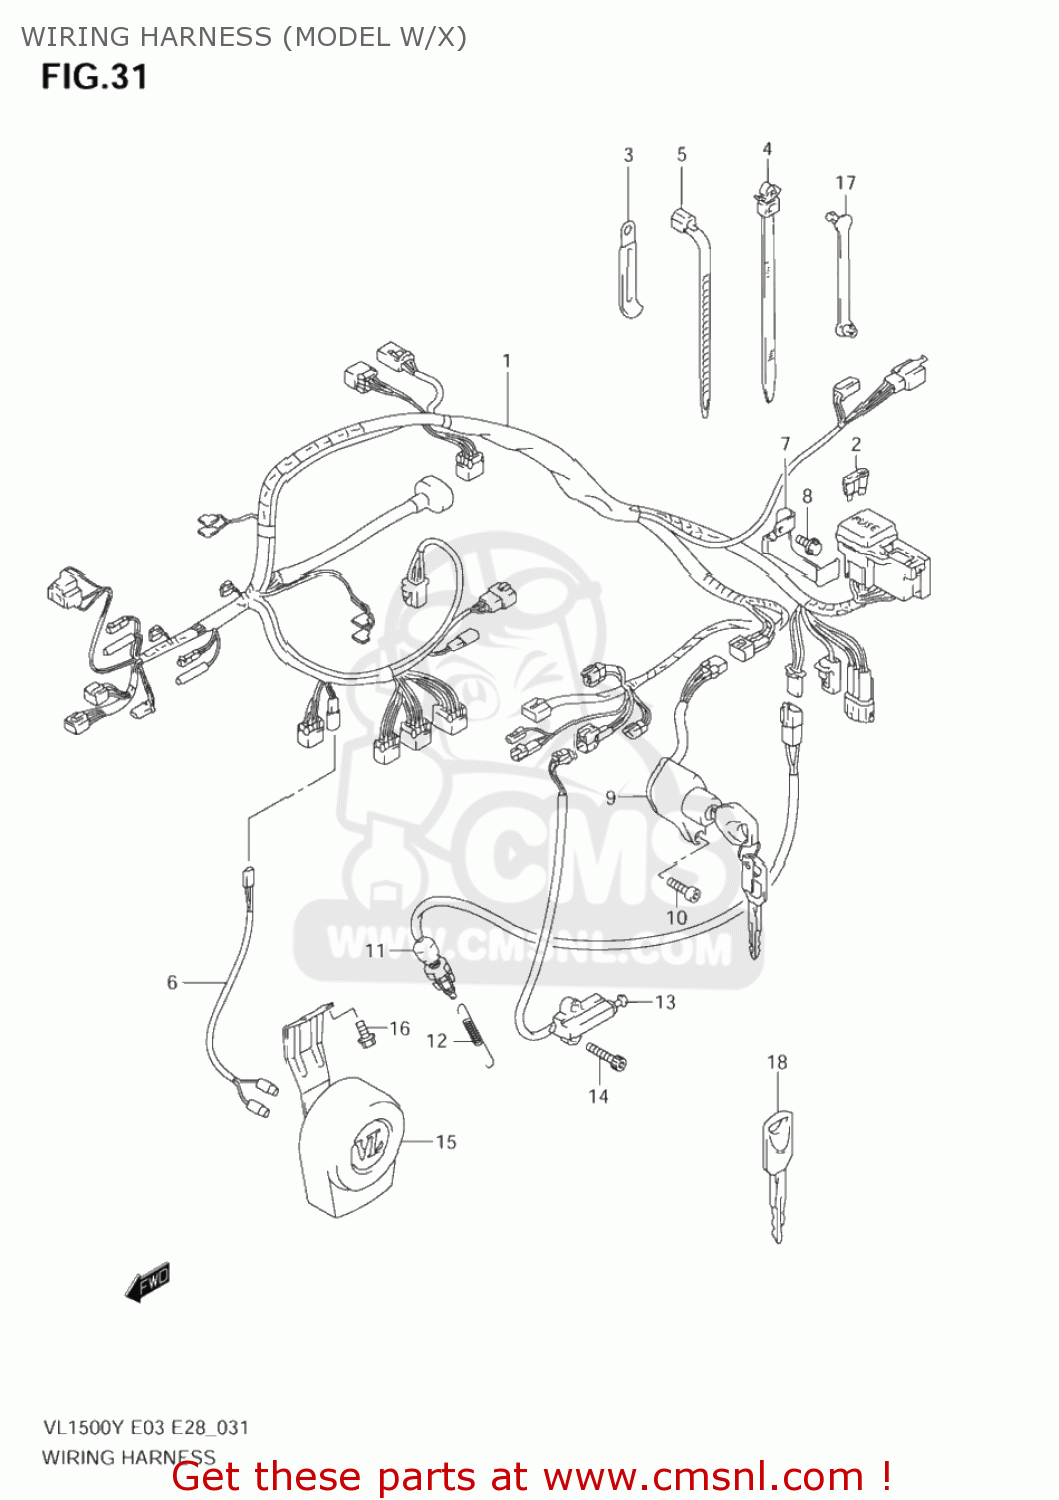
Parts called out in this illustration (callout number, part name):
1	HARNESS,WIRING
2	FUSE(10A)
3	CLAMP(L:45)
4	CLAMP(L:90)
5	CLAMP(L:125)
6	WIRE,HORN LEAD
7	BRACKET,FUSE
8	BOLT
9	SWITCH ASSY,IGNITION
10	BOLT,OIL FILLE
11	SWITCH ASSY,STOP LAMP
12	SPRING,STOP LAMP SWITCH
13	SWITCH ASSY,SIDE STAND
14	SCREW
15	HORN ASSY
16	BOLT
17	CLAMP(L:33)
18	KEY,BLANK
